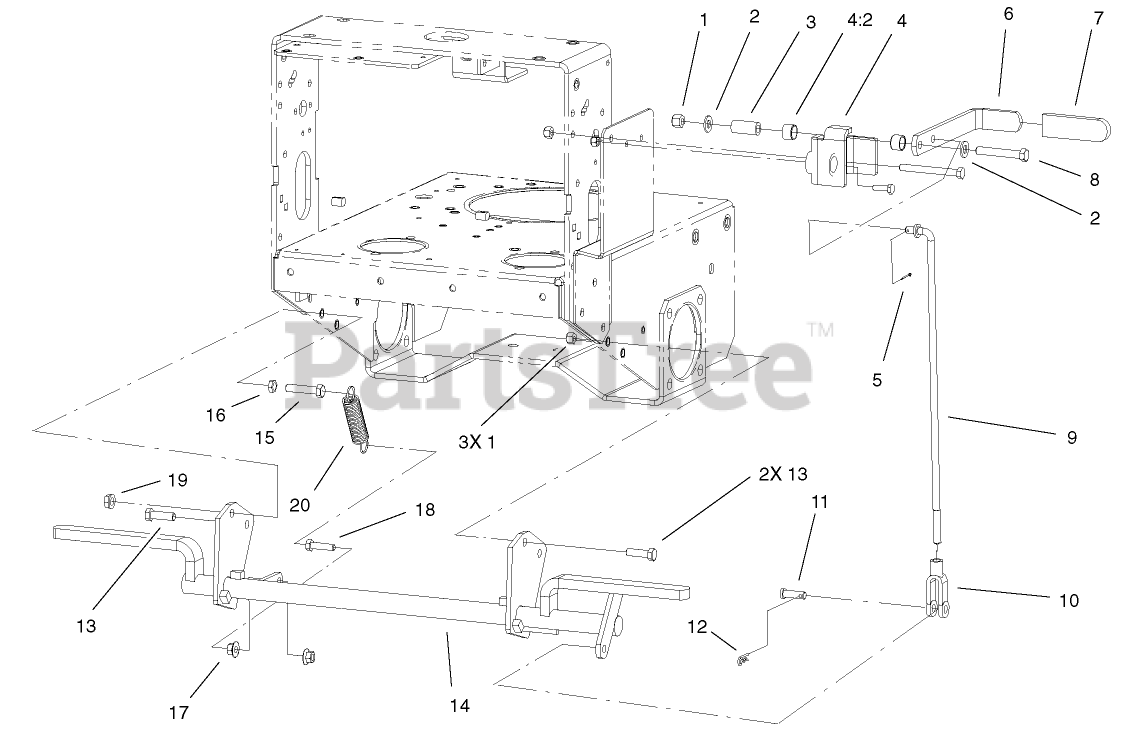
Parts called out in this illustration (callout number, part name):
1	NUT-LOCK, NI
2	WASHER-FLAT
3	BUSHING-PIVOT
4	BRACKET ASM
4:2	SLEEVE-BUSHING
5	PIN-COTTER
6	HANDLE-PARKING BRAKE
7	GRIP-LEVER
8	SCREW-HH
9	ROD-LINK
10	YOKE-LINKAGE, BRAKE
11	PIN-CLEVIS
12	PIN-COTTER
13	SCREW-HH
14	BRAKE ASM
15	SCREW-HH
16	NUT-JAM
17	NUT-HF
18	SCREW-HH
19	NUT-HHF, WHIZ
20	SPRING-IDLER
